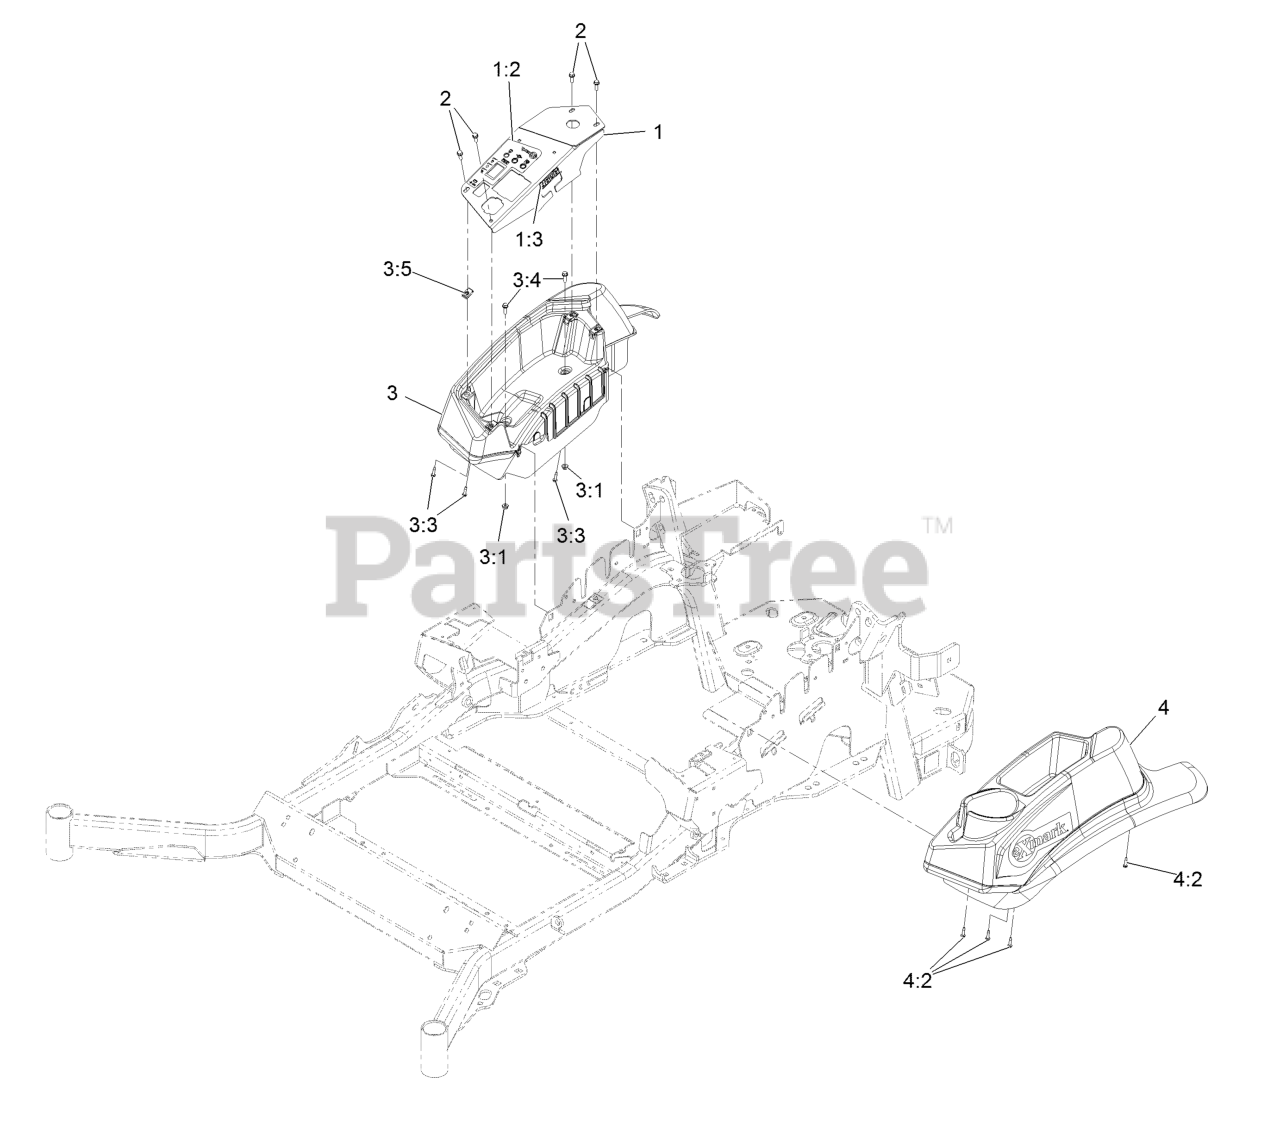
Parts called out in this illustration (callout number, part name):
1	CONTROL PANEL W/DECAL
1:2	DECAL-CONSOLE RED
1:3	DECAL-FUSES
2	SCREW-HWH
3	CONSOLE,RH NARROW ASM
3:3	SCREW,THD FORM,HWH
3:4	SCREW-HWH
3:5	Nut-Retainer-Panel 1/4-20
4	CONSOLE.LH NARROW ASM
4:2	SCREW,THD FORM,HWH
